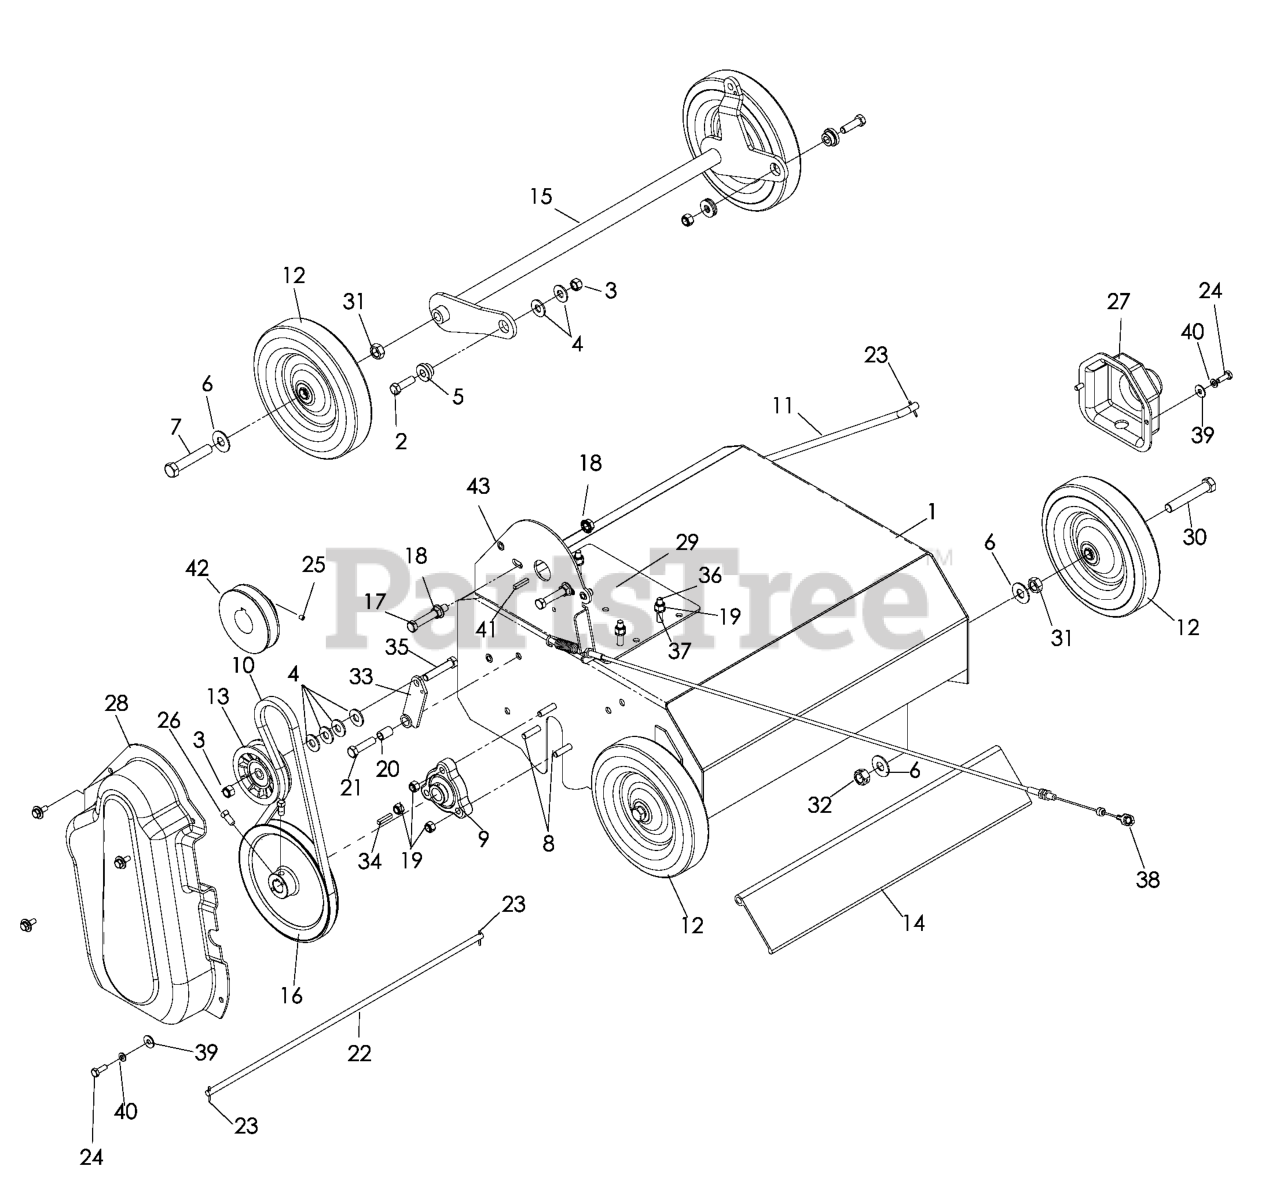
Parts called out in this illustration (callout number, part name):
1	KIT, BODY W/DECALS
2	HCS 3/8C X 1 1/4 GR5
3	NUT 3/8-16 NYLOC
4	WASHER 3/8 FLAT
5	BUSHING RAKE
6	WASHER 1/2 FLAT
7	HCS 1/2C X 2 3/4
8	HCS 5/16C X 1 1/4
9	BEARING, FLANGED
10	BELT, DRIVE RAKE/SLICER DFS
12	WHEEL 8 X 1 3/4 RAKE
13	PULLEY, IDLER RAKE & ZTR
14	DEFLECTOR SHIELD
15	FRONT AXLE ORANGE
16	PULLEY, MAIN SHAFT
17	HCS 3/8C X 2 1/2
18	NUT 3/8C WHIZ
19	NUT 5/16 NYLOC
20	BEARING, ONLITE RAKE/DT
21	HCS 3/8C X 1 1/2
22	DEFLECTOR ROD
23	COTTER PIN 3/32 X 3/4
24	HCS 1/4C X 3/4 HCS
25	KPSS 5/16-18 x 3/8
26	SCREW 5/16C X 5/8 SQ HEAD
27	SHAFT GUARD
28	BELT GUARD
29	BACKING PLATE, BLUE
30	SCREW, 1/2C X 3 HEX CAP
31	NUT 1/2 HEX JAM
32	NUT 1/2-13 HEX CNTRLK GR 5 ZD
33	IDLER, ARM, BLACK
34	KEY, 3/16 SQUARE
35	HCS 3/8C X 2
36	HCS 5/16C X 1 3/4
37	WASHER.LOCK.HVY.HLCL.SPR.5/16
38	CABLE POWER RAKE
39	WASHER 1/4 FLAT
40	LOCKWASHER 1/4"
41	KEY, 3/16 SQUARE
42	ENGINE PULLEY - 5.5 HP
43	KNURLED INSERT
